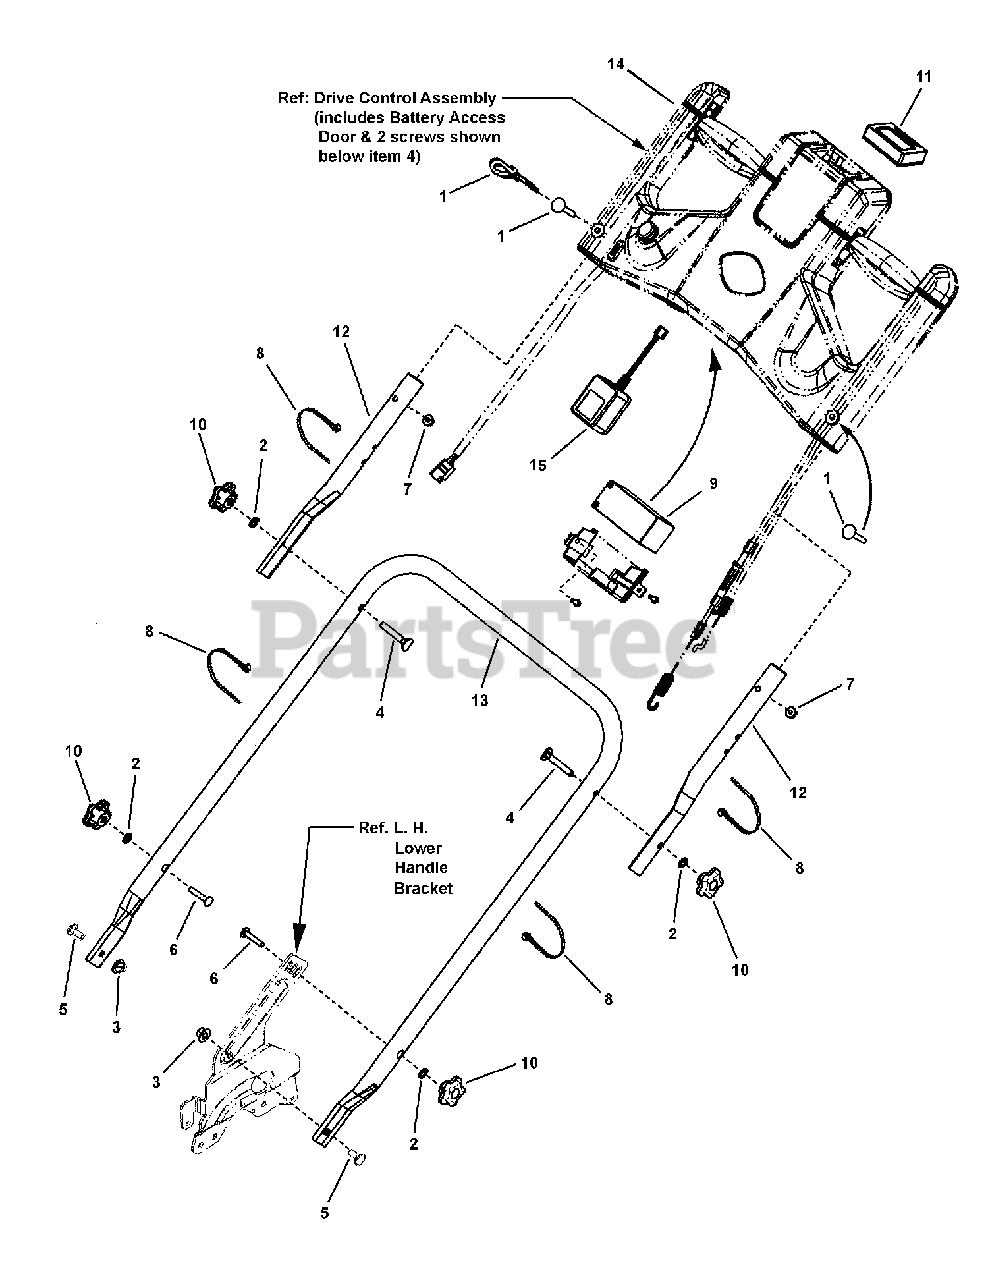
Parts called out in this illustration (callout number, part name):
1	BOLT, 1/4-20 x 1-3/4" Round Head Square Neck, GR 2, YZ
1	GUIDE, Rope, 1/4-20 x 1.8"
2	WASHER, 5/16" Internal Tooth Lock
3	NUT, 5/16-18 Large Flange Center Lock
4	BOLT, 5/16-18 x 2" Curved Head Square Neck, GR 2
5	BOLT, 5/16-18 x 3/4" Round Head Short Square Neck, GR 5, YZ
6	BOLT, 5/16-18 x 1-3/4" Round Head Square Neck Carriage
7	NUT, 1/4-20 Hex Flange (Esna), YZ
8	WIRE TIE, 11 Inch Standard Black Nylon
9	BATTERY, 1.3A/Hr
10	KNOB, Handle, 5-Prong (5/16-18 internal threads)
11	METER, Service Indicator
12	HANDLE, Connecting, 21"/22" WBM
13	HANDLE, Lower, WBM, RD
14	ASSEMBLY, Drive Control (MY 2010)
15	CHARGER, Battery, 120V AC, Output 14V DC, 260mA
15	CHARGER, Battery, 230V AC, 50 Hz, Output 12V DC, 750mA (Euro)
